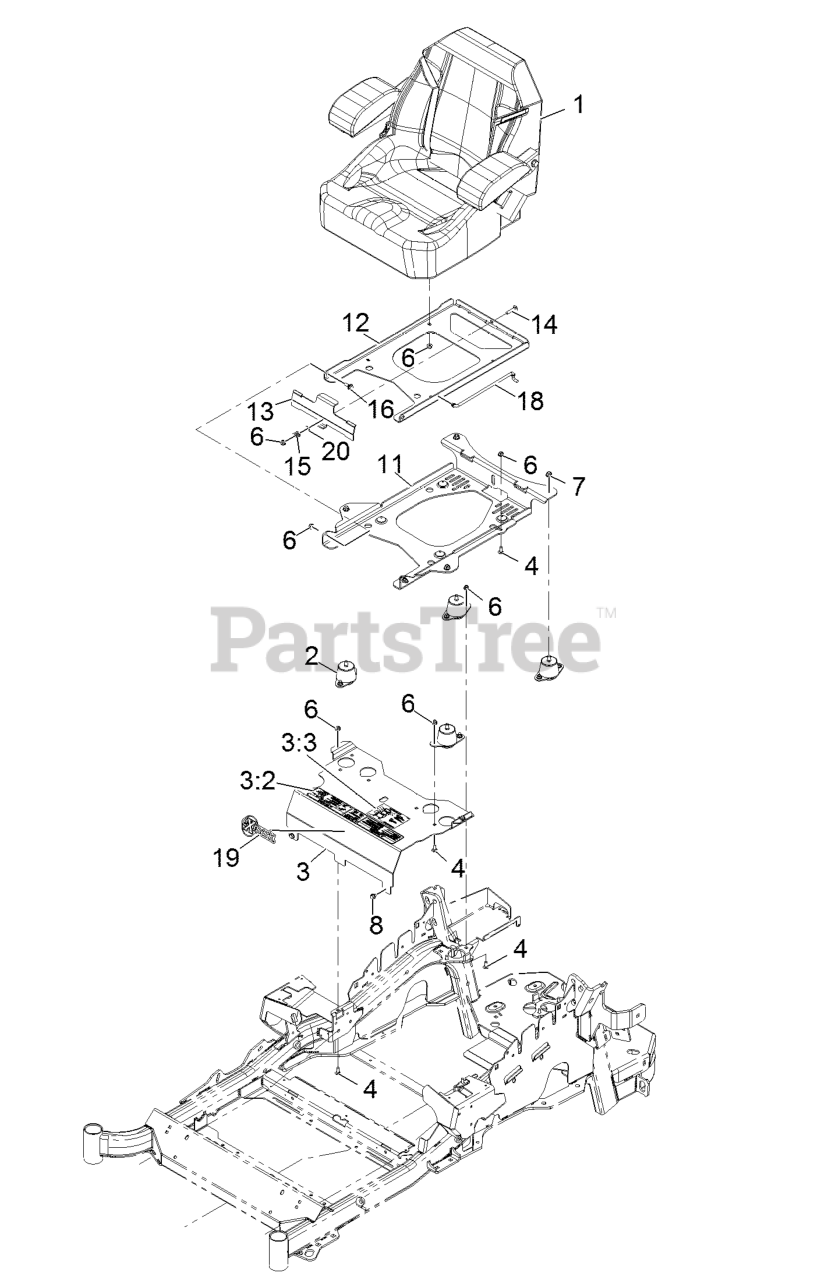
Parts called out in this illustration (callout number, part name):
2	ISOLATOR-SEAT
3	MOUNT-SEAT
3:2	DECAL-CONSOLE
3:3	DECAL-SERVICE AID
4	SCREW-CARR
6	NUT-HF, NI
7	NUT-HF, NI
11	PLATE-TILT, SEAT SUPPORT
12	PLATE-FRAME, SEAT
13	PLATE-LATCH, SEAT
14	BOLT-CARR
15	SPRING-COMPRESSION
16	SCREW-SHOULDER
18	ROD-PROP
20	WASHER-PLAIN
